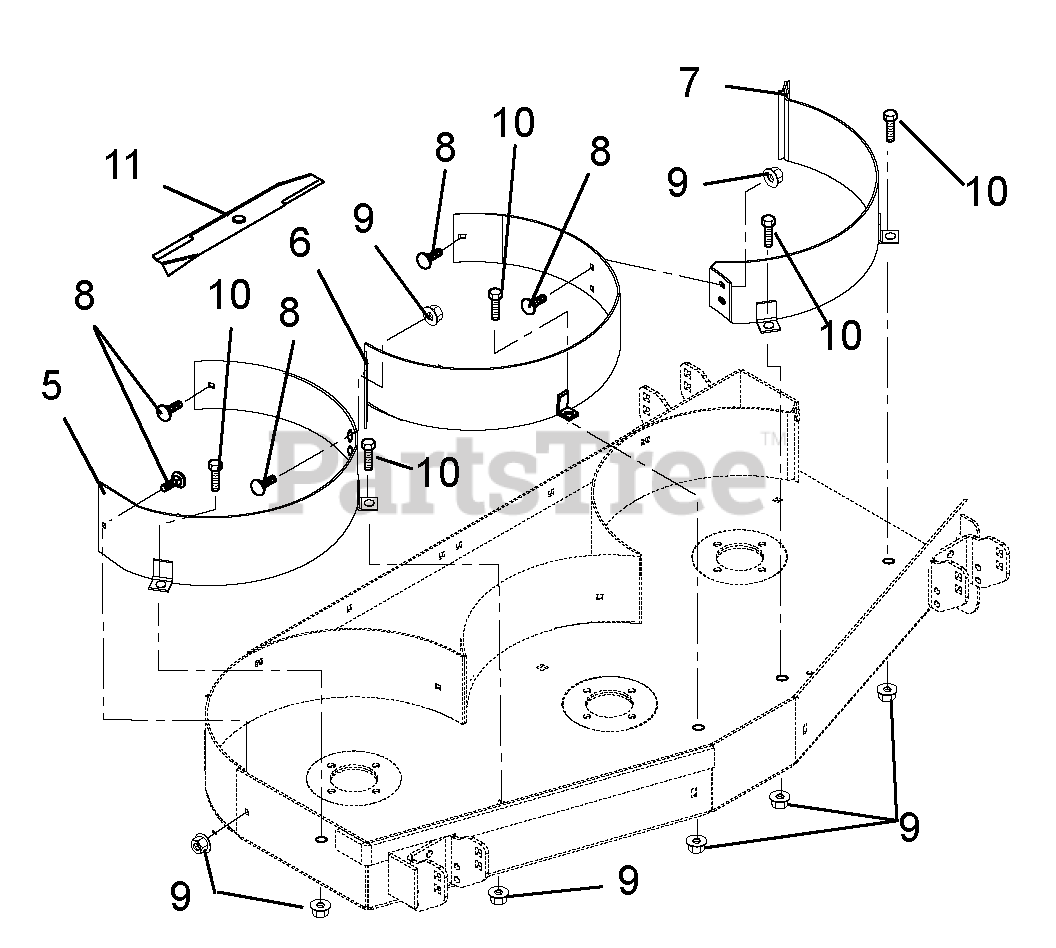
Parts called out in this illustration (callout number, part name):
5	BAFFLE-MULCH-LEFT FRONT-32"
5	BAFFLE-MULCH-LEFT FRONT-36"
5	BAFFLE-MULCH-LEFT FRONT-44"
5	BAFFLE-MULCH-LEFT FRONT-48"
5	BAFFLE-MULCH-LEFT FRONT-52"
5	BAFFLE, MULCH 34" FRONT LH
6	BAFFLE-MULCH-CENTER FRONT-44"
6	BAFFLE-MULCH-CENTER FRONT-48"
6	BAFFLE-MULCH-CENTER FRONT-52"
7	BAFFLE-MULCH-RIGHT FRONT-32"
7	BAFFLE-MULCH-RIGHT FRONT-36"
7	BAFFLE-MULCH-RIGHT FRONT-44"
7	BAFFLE-MULCH-RIGHT FRONT-48"
7	BAFFLE-MULCH-RIGHT FRONT-52"
7	BAFFLE, MULCH 34" FRONT RH
8	@BLT-RDHDSQNK .31-18X.75 G5YZ
9	@NUT-LK-TOP-FLG .31-18 YWZC
10	@BLT-HEX .31-18X.75 GR5 YWZC
11	BLADE, MULCH 16.25
11	BLADE, MULCH 18.00"
11	BLD,MULCHING 50" MWR
